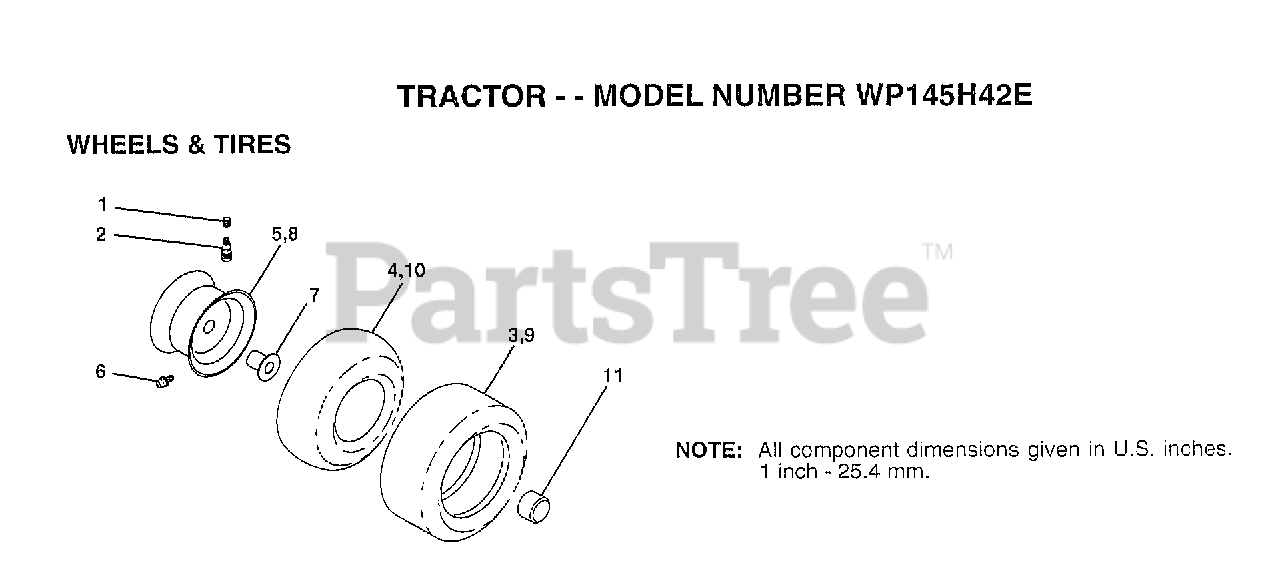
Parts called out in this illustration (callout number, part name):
1	VALVE CAP
2	VALVE STEM LT
4	TUBE.5.3/4.5/6
5	"RIM,FRT T"
6	FITTING LT
7	"FLANGE, BEARING"
8	"RIM 8"""
9	TIRE.20X8-8
10	TUBE.18X9.5-8
11	HUB CAP
